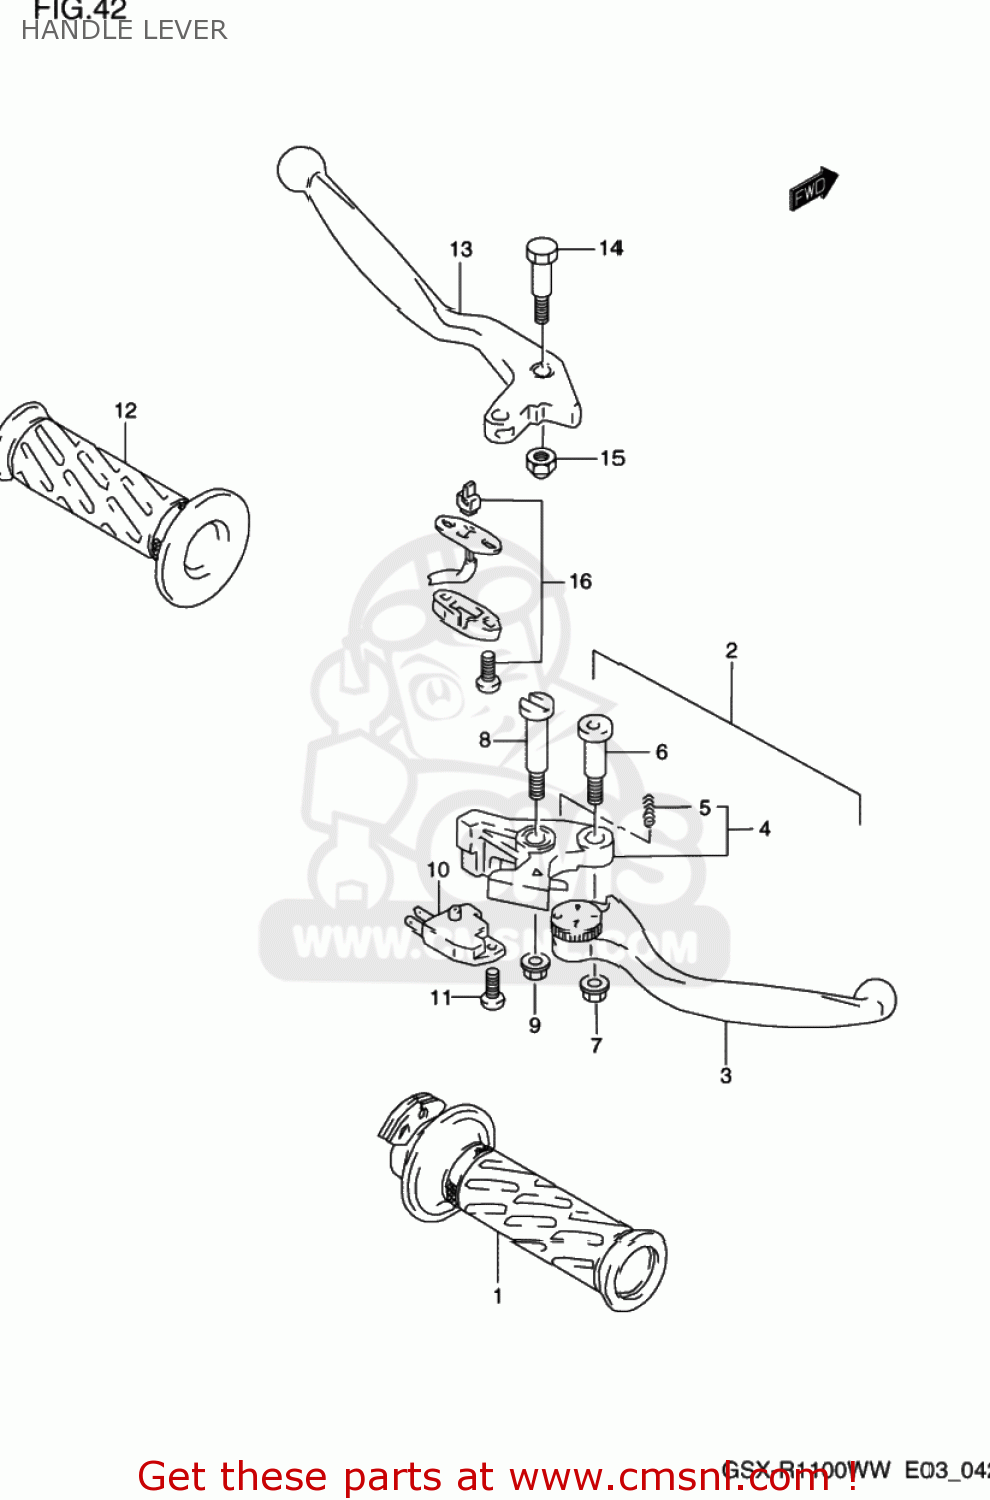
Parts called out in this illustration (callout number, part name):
1	GRIP,THROTTLE
2	LEVER ASSY,BRAKE
3	LEVER,ADJUST
4	KNOCKER
5	SPRING
6	BOLT,LEVER
7	NUT
8	BOLT,LEVER PIVOT
9	NUT
10	SWITCH ASSEMBLY,STOP
11	SCREW
12	GRIP,LEFT
13	LEVER,CLUTCH (SILVER)
14	BOLT,LEVER
15	NUT
16	SWITCH ASSY,CLUTCH
